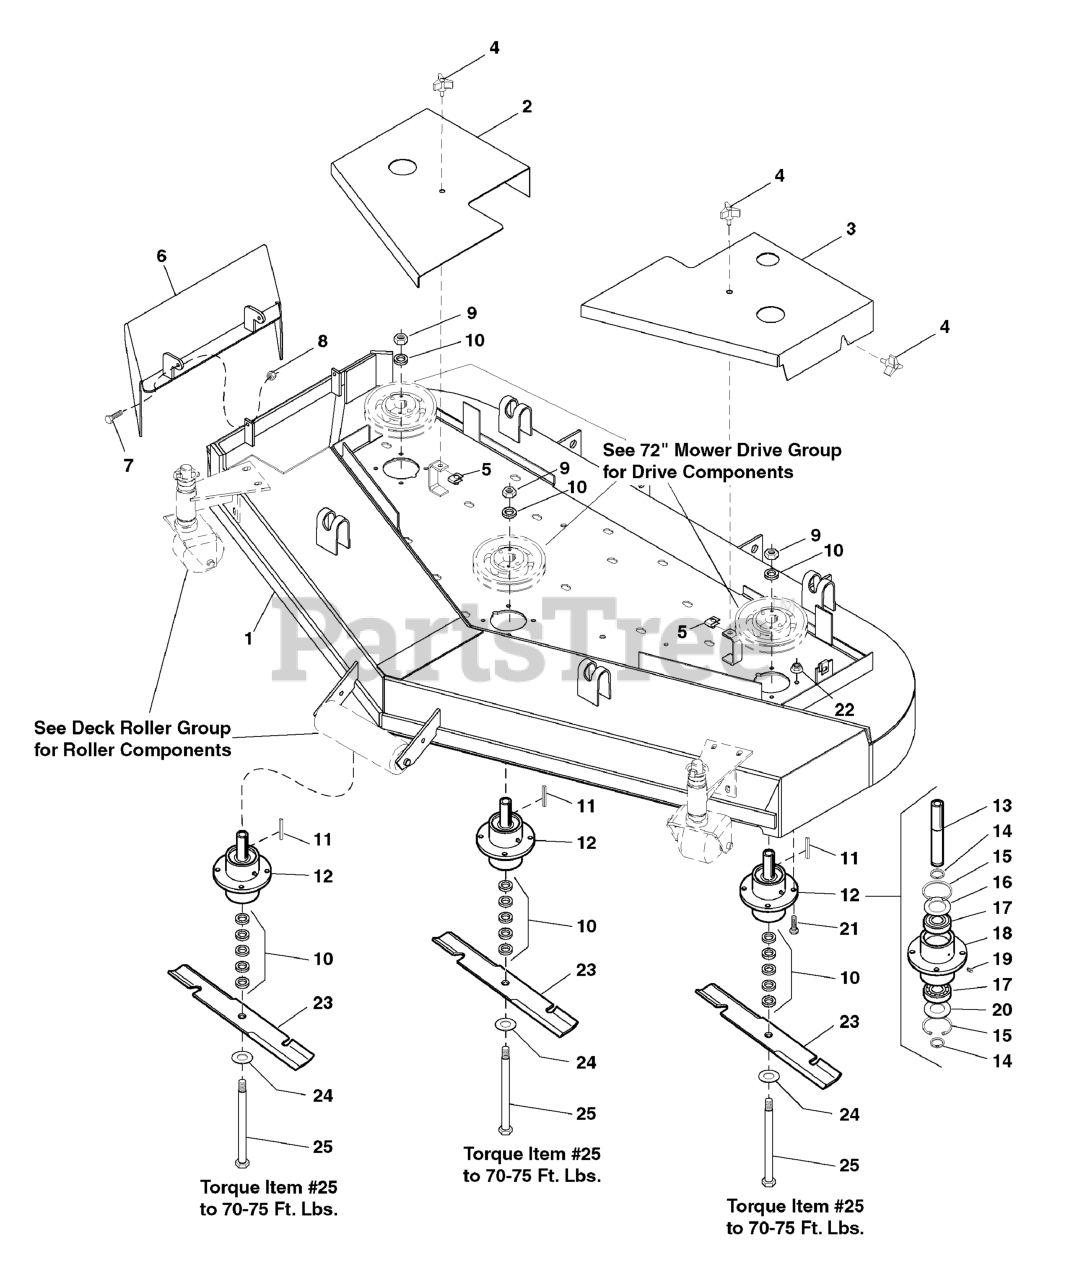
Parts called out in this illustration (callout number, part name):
1	72" MOWER HOUSING
2	SPINDLE COVER-LH
3	SPINDLE COVER-RH
4	KNOB
5	BODY CLIP, 5/16-18-7GA MATERIAL
6	DISCHARGE CHUTE
7	BOLT, 5/16-18 X 1 GD5 YZ
8	NUT, 5/16-18 Hex Nylon Lock
9	NUT, 5/8-11 Hex
10	SPACER, .63 x 1.06 x .23
11	KEY, 1/4 SQ. X 2-1/2
12	SPINDLE ASSEMBLY, Complete
13	SPINDLE SHAFT
14	SNAP RING, External
15	SNAP RING, Internal
16	SPINDLE WASHER, Top
17	BEARING
18	SPINDLE HOUSING
19	GREASE FITTING
20	SPINDLE WASHER, Bottom
21	BOLT, 5/16-18 x 1-1/4
22	NUT, 5/16-18 HEX SERRATED FLANGE (LARGE)
23	BLADE, 25" (SET OF THREE)
24	WASHER, 5/8" USS
25	BOLT, 5/8-11 x 9-1/2
